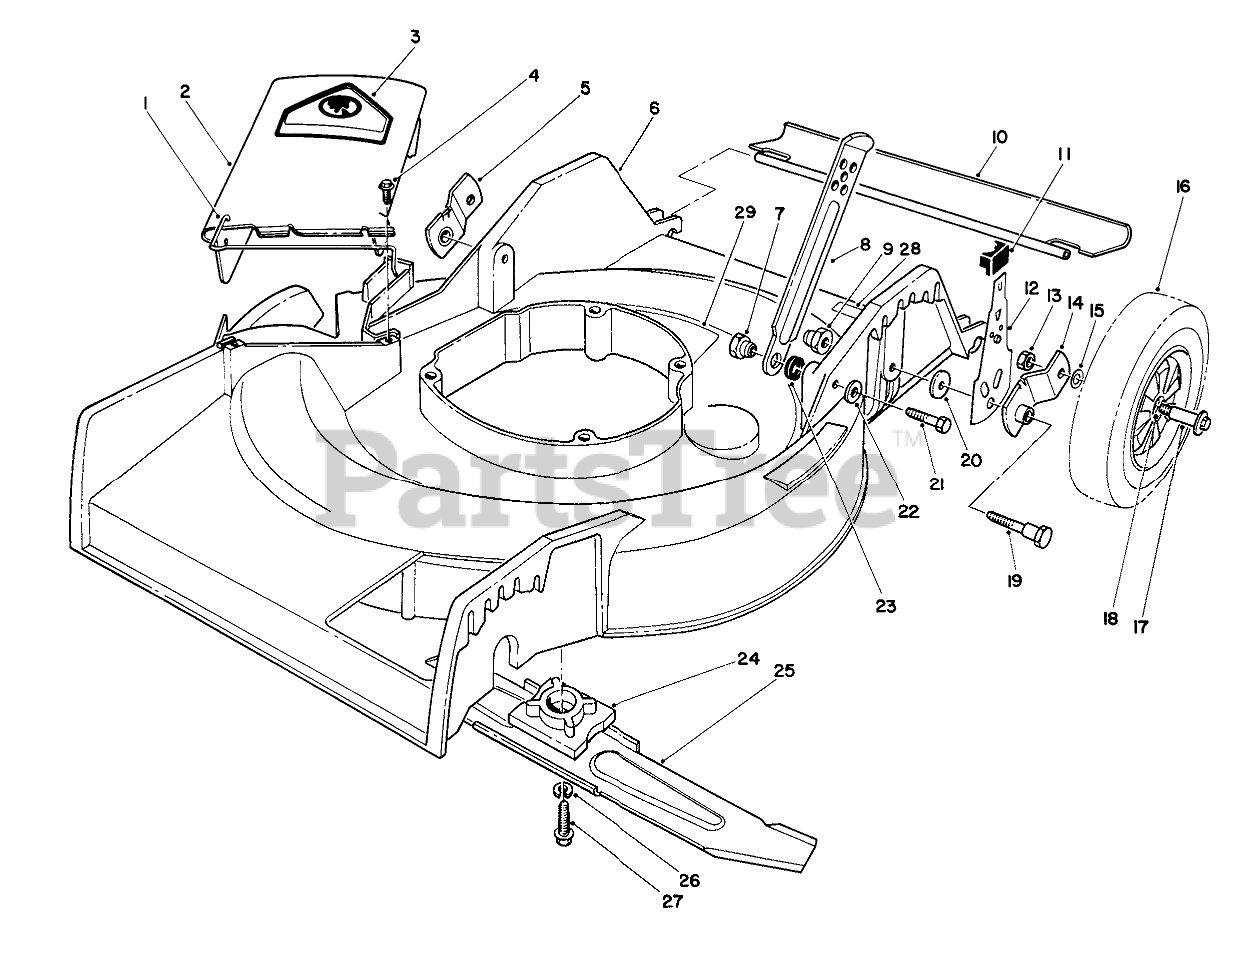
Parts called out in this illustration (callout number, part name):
1	SPRING HINGE
2	Deflector Assembly (Incl. Ref. #1 & 3)
3	DECAL-DANGER
4	SCREW-HWH
5	Pivot Arm
6	Housing-21" (Incl. Ref. #28 & 29)
7	HANDLE PIVOT NUT
8	Latch-Handle
9	HANDLE PIVOT NUT
10	SHIELD - TRAILING
11	KNOB-ARM
12	REAR SPRING ARM ASM
13	NUT-LOCK
14	Pivot Arm
15	WASHER
16	Wheel & Tire Assembly (Incl. Ref. #18)
17	WHEEL BOLT
18	BUSHING
19	5/16-18 PIVOT SCREW
20	PIVOT WASHER
21	SCREW-HH
22	WASHER-LOCK
23	SPACER
24	BLADE RETAINER
25	Blade
26	WASHER-LOCK
27	SCREW-HH
28	DECAL-WARNING
29	DECAL-INSTRUCTION, SAFETY
